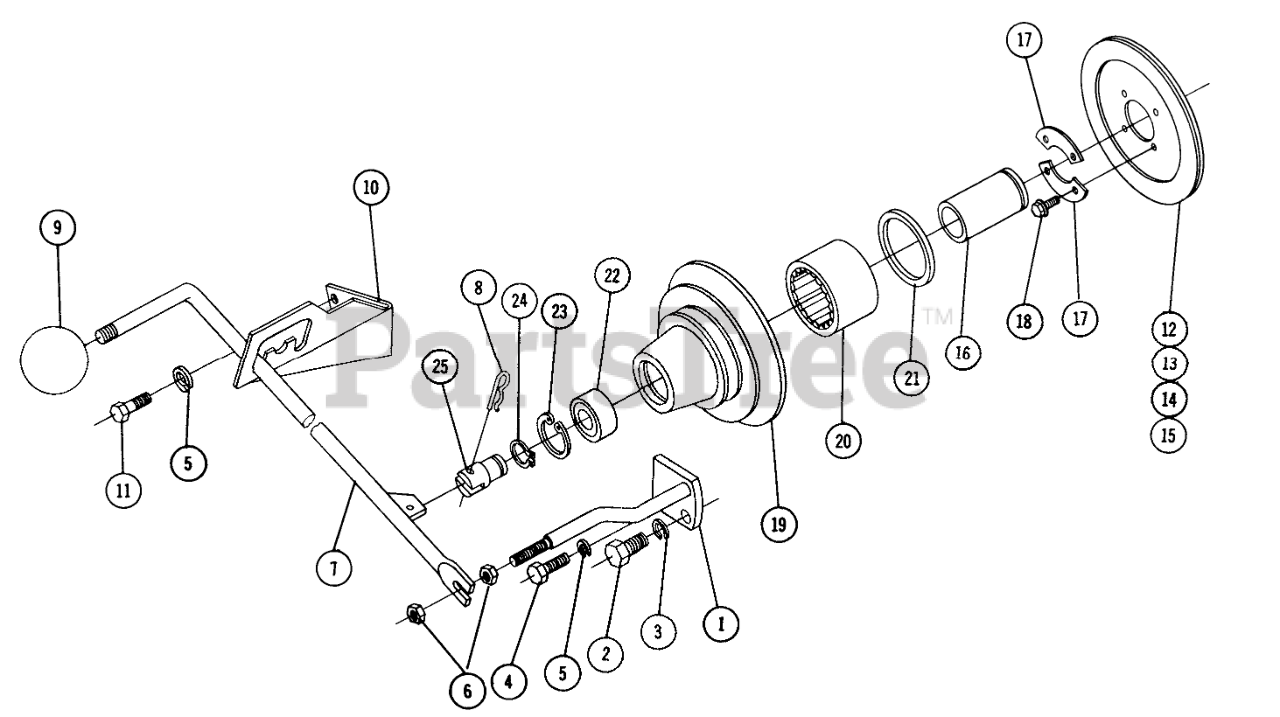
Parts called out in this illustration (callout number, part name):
1	Assembly-Plate & Rod
2	Bolt Hex 7/16-4 x 3/4
3	Lockwasher 3/8
4	Bolt 5/16-18 x
5	Lockwasher
7	ROD ASSY
8	Hairpen
9	Knob
10	Bracket
11	Bolt Hex 5/16-18
12	L/A CLUTCHPLATE&FACI
13	Clutch Plate
14	CLUTCH FACING
15	RIVET-BRASS
16	RACE-BEARING
17	RETAINER
18	Bolt, 1/4-20 Whizlock
19	Housing-Clutch
20	Seal
21	SEAL-OIL
22	Bearing
23	Ring-Snap
24	RING-SNAP, EXTERNAL
25	SHAFT
26	DECAL
